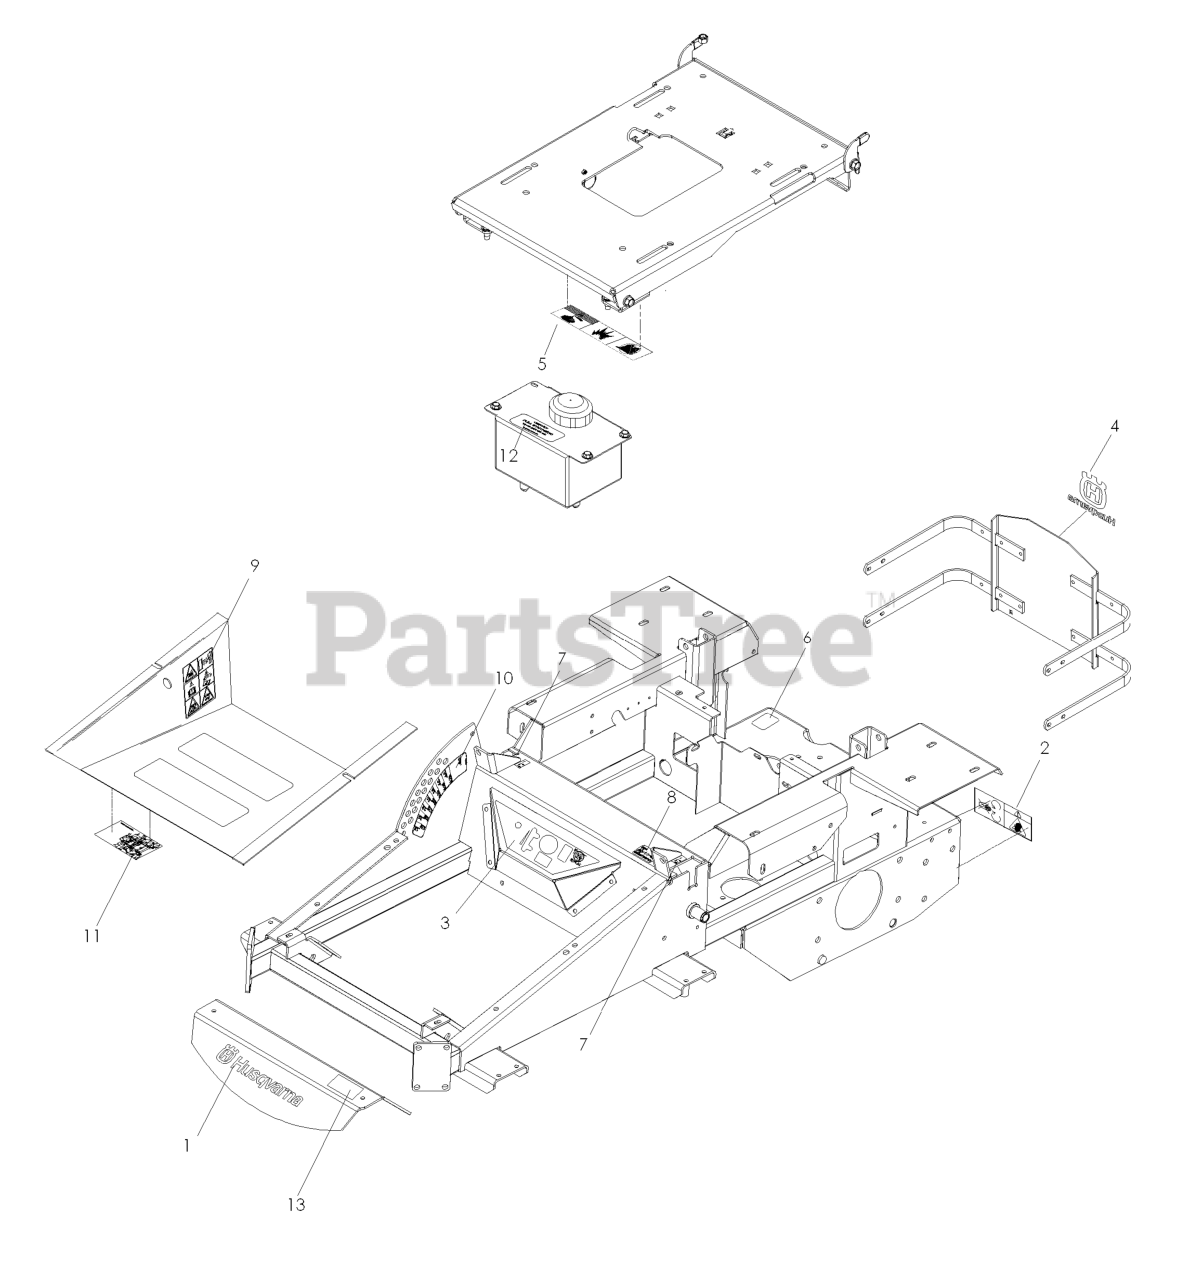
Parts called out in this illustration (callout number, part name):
1	DECAL, HUSQ 12" BLUE
2	DECAL, BELT DRIVE
3	DECAL, CONSOLE
4	DECAL, CROWN H 5-1/4 SILVER
5	EURO DECAL-BATTERY WARNIN6
6	DECAL, PROP. 65
7	DECAL, MOTION CONTROL
8	DECAL, F.S.T.
9	DECAL, WARNING
10	DECAL, HEIGHT ADJ
11	DECAL, SERVICE
12	DECAL, OIL TANK
13	DECAL, IZ21
13	DECAL, IZ25
